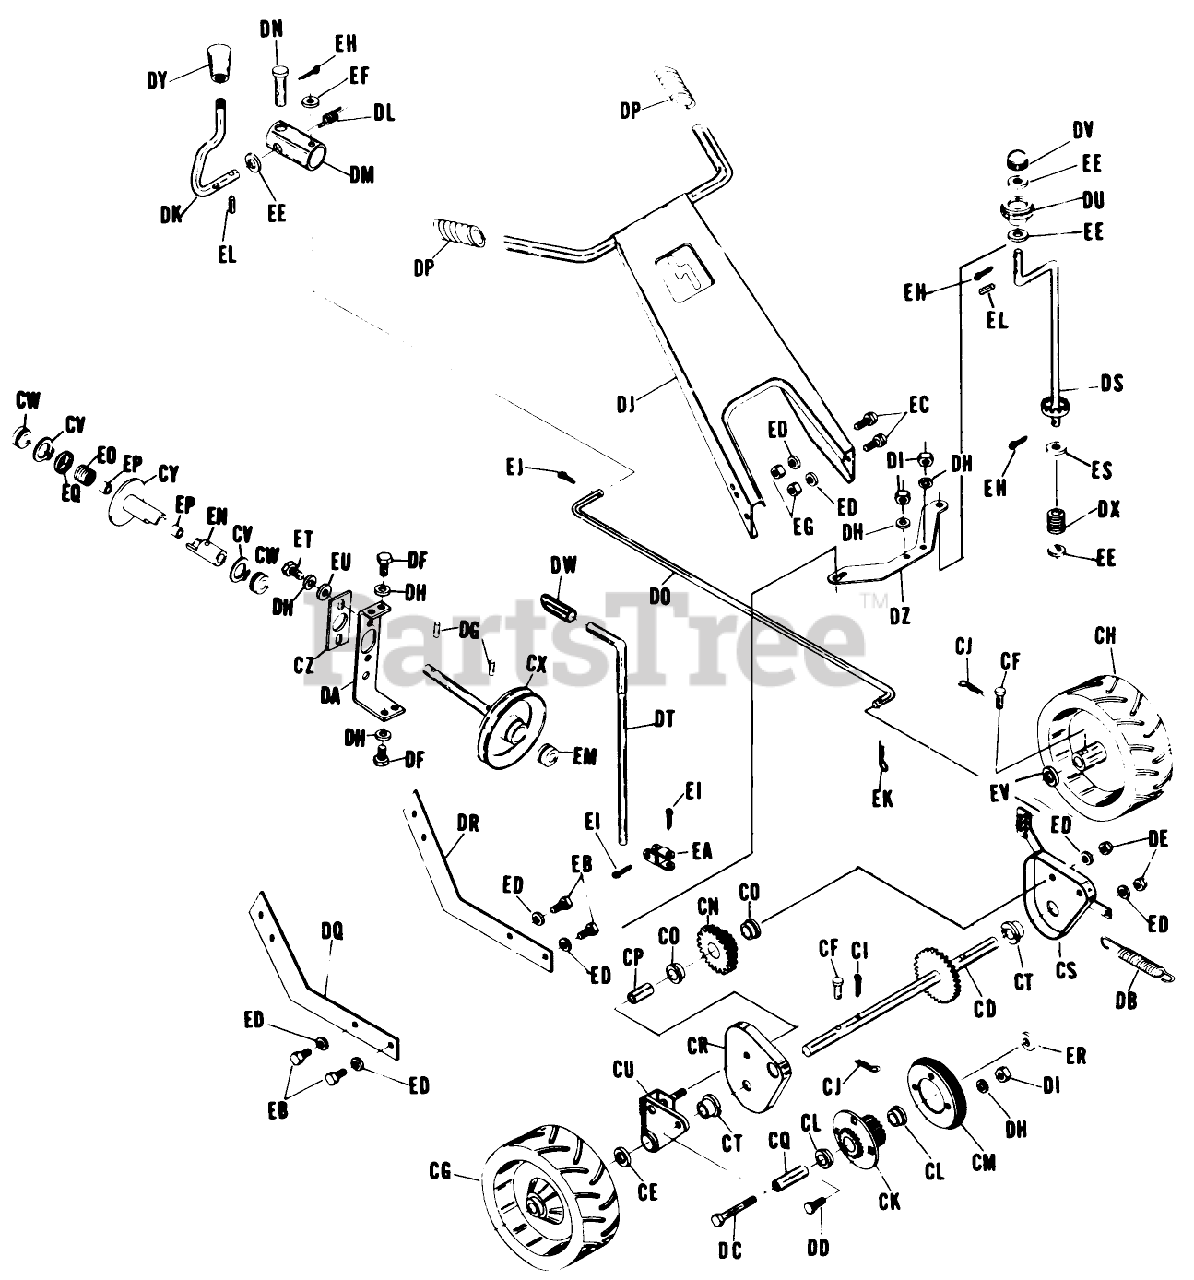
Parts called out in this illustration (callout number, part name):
CU	Traction Drive Arm Assembly w/Flange Bearing
CX	Traction Drive Shaft Assy
DA	Bearing Support
DC	3/8-16 x 3 1/4 Hex. Hd. Cap Screw, Plated
DE	3/8-16 Lock Nut, Plated
DF	5/16-18 x 1/2 Hex. Hd. Cap Screw, Plated
DG	3/16 x 1" Roll Pin
DH	5/16 Spring Lock Washer, Pl.
DI	5/16-18 Hex. Nut, Plated
DM	Control Tube
DS	Chute Control Assembly
DT	Auger Clutch Rod Assy
DZ	Control Panel
EB	3/8-16 x 1/2 Hex. Hd. Cap Screw, Plated
ED	3/8 Spring Lock Washer, Pl.
EE	3/8 SAE Flat Washer, Plated
EF	1/4 SAE Flat Washer, Plated
EG	3/8-16 Hex Nut, Plated
EH	1/8 x 3/4 Cotter Pin, Plated
EJ	3/32 x 3/4 Cotter Pin, Plated
EL	1/8 x 3/4 Roll Pin, Plated
ET	5/16-18 x 5/8 Hex. Hd. Cap Screw, Plated
EU	5/16 SAE Flat Washer, Pl.
